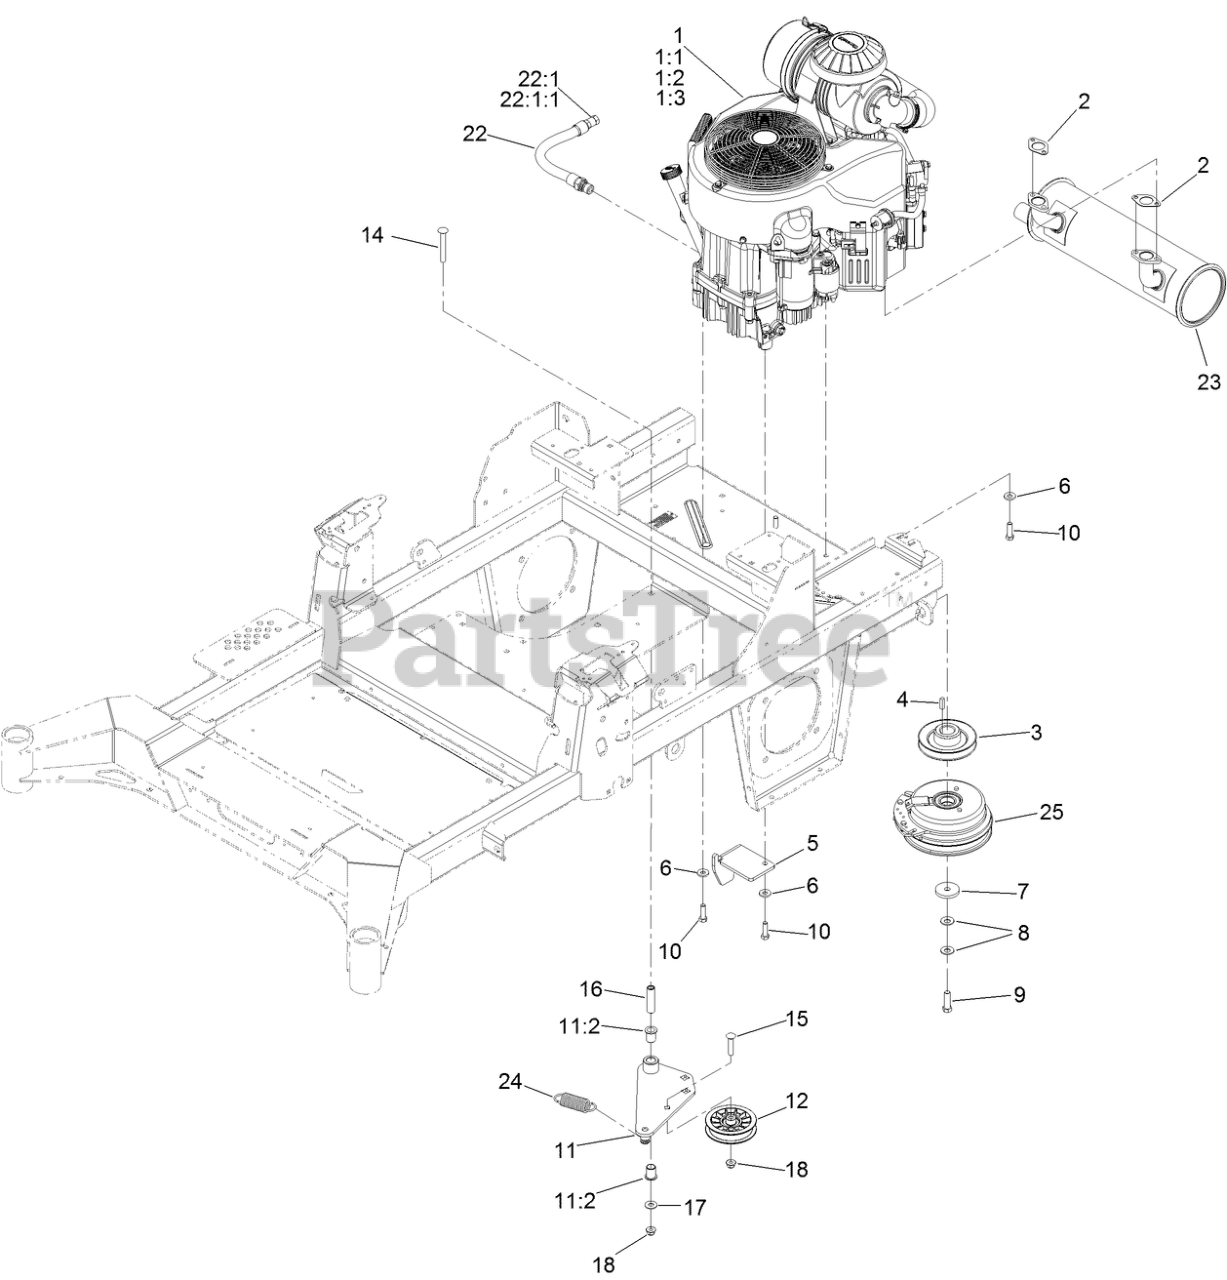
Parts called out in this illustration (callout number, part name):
1	ENGINE-KAWASAKI, FX801V-S04-R
1:1	KAWASAKI 49065-7010 ENGINE OIL FILTER
1:2	KAWASAKI 11013-7044 ENGINE AIR FILTER
1:3	KAWASAKI 11013-7045 SAFETY FILTER
2	GASKET-EXHAUST
3	SHEAVE, W/HUB
5	ANCHOR-CLUTCH
6	WASHER-BELLEVILLE
7	WASHER-CLUTCH
8	WASHER-SPRING
9	SCREW-HH, W/LOCTITE
10	SCREW-HH
11	IDLER ARM ASM
11:2	BUSHING-FLANGE
12	PULLEY-FLAT IDLER
14	SCREW-CARR
15	SCREW-CARR
16	BUSHING, IDLER PIVOT
17	WASHER-FLAT
18	NUT-HF, NI
22	ENGINE OIL DRAIN HOSE ASM
22:1	PLUG-HH
22:1:1	O-RING
23	MUFFLER
24	SPRING-IDLER
